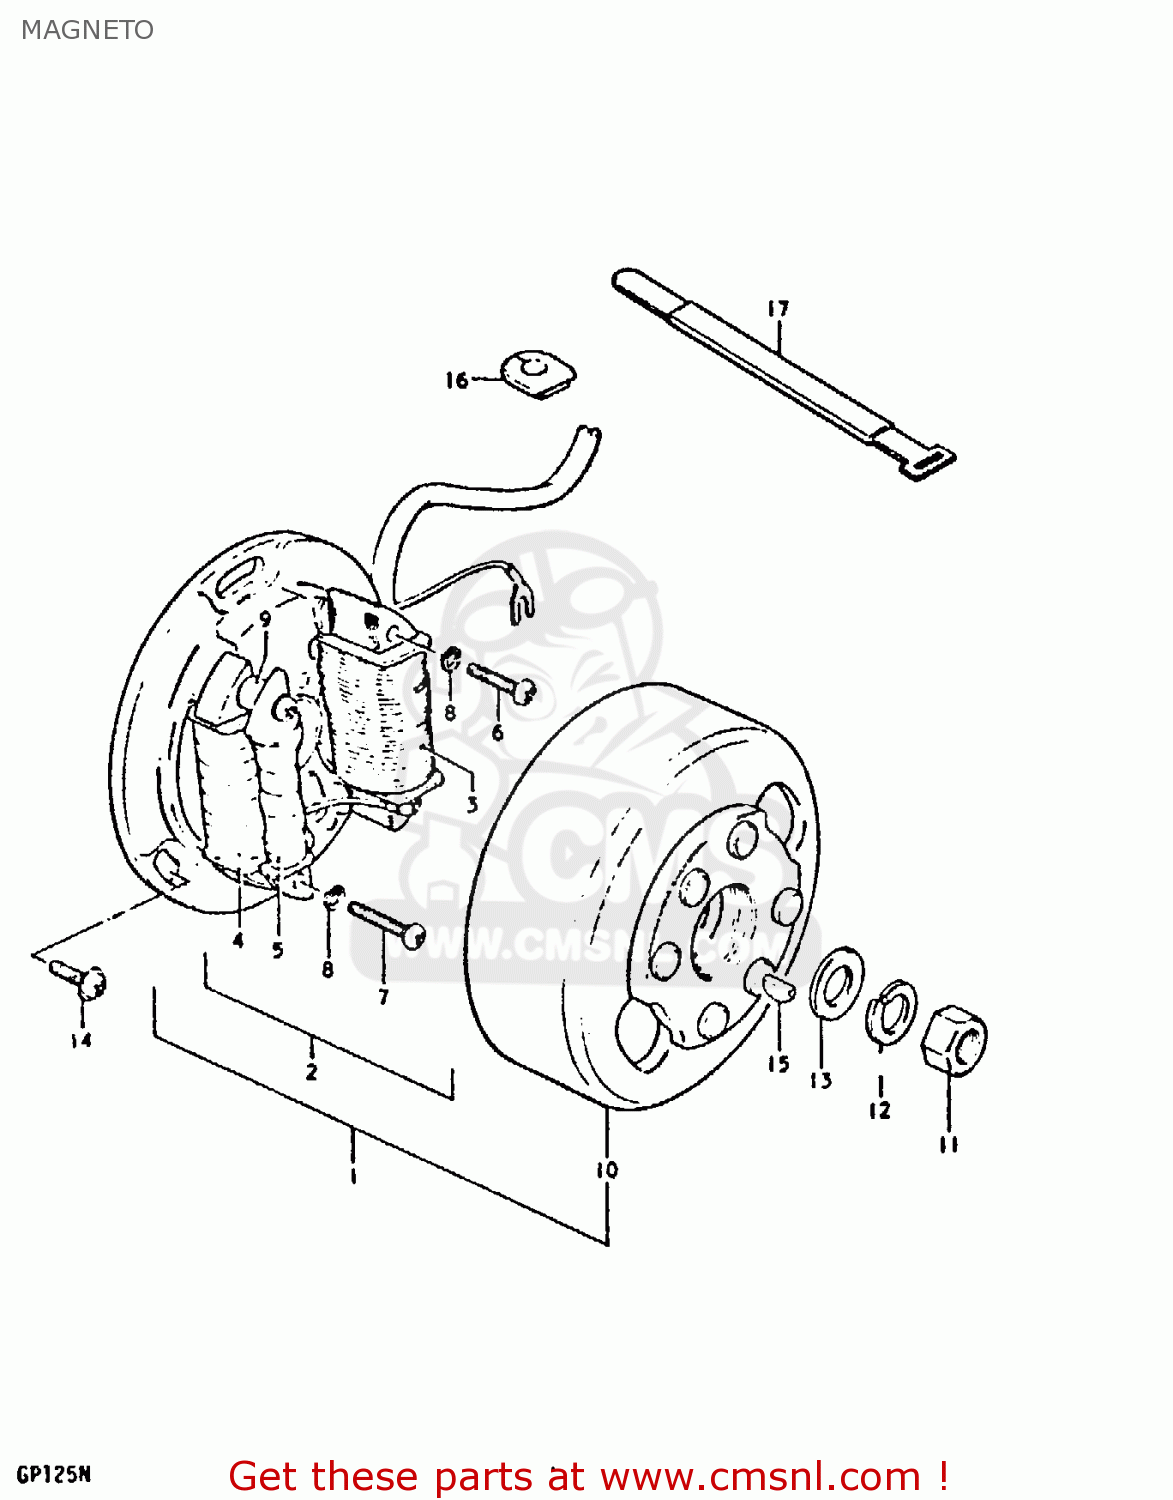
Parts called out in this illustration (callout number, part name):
11	NUT (10MM)
12	LOCK WASHER
13	WASHER
14	SCREW(5X14)
15	KEY
16	GROMMET
17	CLAMP
